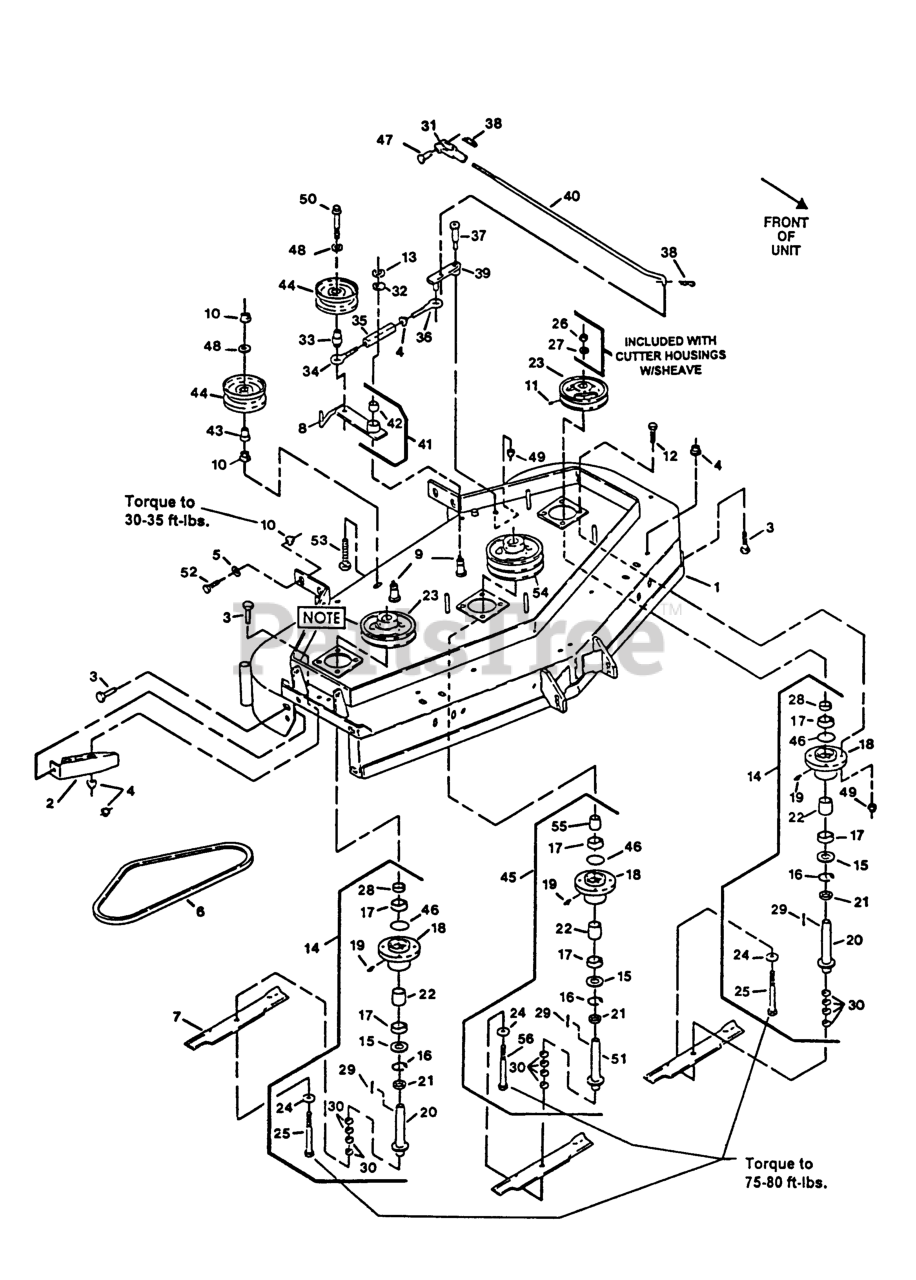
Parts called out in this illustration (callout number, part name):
2	WLD, DISCHARGE BAFFLE
11	SCREW-SET
14	ASM,HOUSING CUTTER
15	SEAL,DUST
16	RING,SNAP WLDS N5000-244
17	BEARING,HD SPINDLE
18	HOUSING,CUTTER
21	SPACER,BEARING &SPINDLE
22	SPACER,BRG/BRG
24	WASHER-SPRING
25	SCREW-CAP, HH
27	WASHER-RETAINER, SHEAVE
31	YOKE-ADJUSTABLE
32	WASHER-SPINDLE
33	BUSHING-ENGAGEMENT
34	EYEBOLT-THREAD, LH
35	BODY-TURNBUCKLE
36	EYEBOLT-THREAD, RH
37	BOLT,SHLDR KSKH
38	PIN-COTTER
42	BEARING,POWDERED METAL
43	BUSHING,IDLER
47	PIN-CLEVIS
53	BOLT,TAP HH3/8-16X2-1/4
55	SPACER,BEARING/SHEAVE
56	SCRW,CAP HH 5/8-18X8.5
